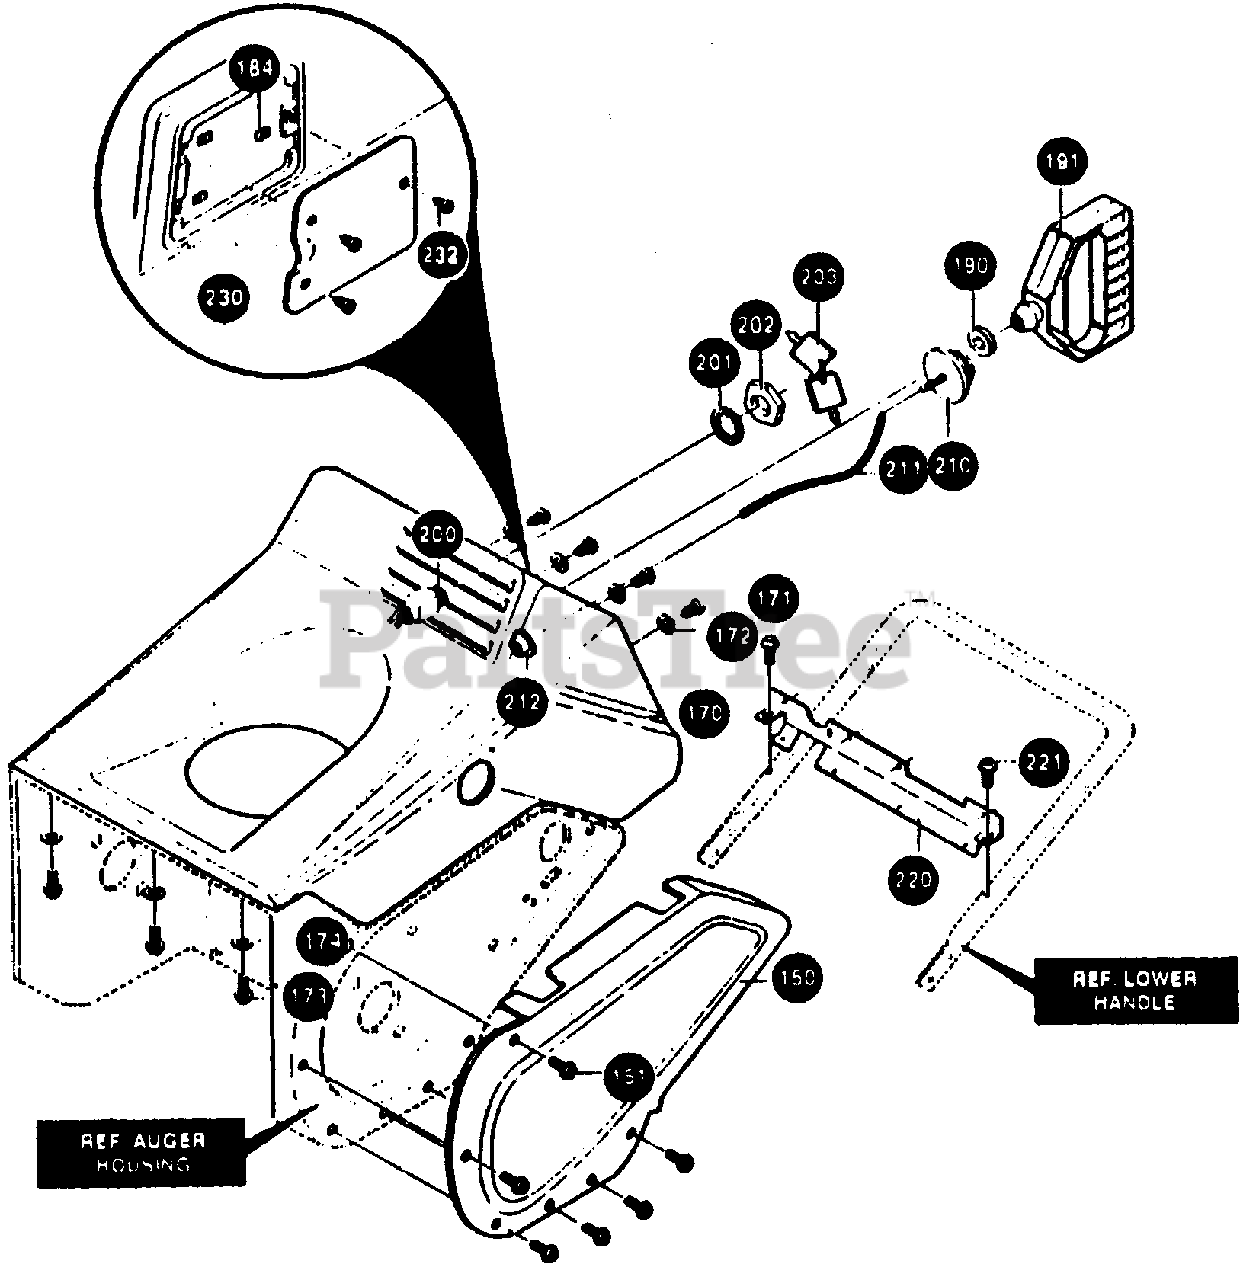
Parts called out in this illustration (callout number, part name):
150	COVER, BELT 2CY
151	SCREW, 10-24X.38 SLHWATAP
170	COVER, TOP
171	SCREW, #1O-24X .63
172	WASHER, FLAT .203X .56X.04O
173	SCREW, #10-14X.63
174	WASHER, FLAT .250X .56X.049
184	NUT, THIN "U" TYPE
190	GROMMET & WASHER
191	GRIP, MITTEN
200	SWITCH, IGNITION
201	WASHER, REGINTLK.640X1.1X.05
202	NUT, 5/8-32
203	2 KEYS & RING
210	PRIMER, ENGINE
211	HOSE, PRIM
212	NUT, 1/4-20
220	BRACKET, SHROUD
221	SCREW, #10-24X .63
232	SCREW #10-16X.75
